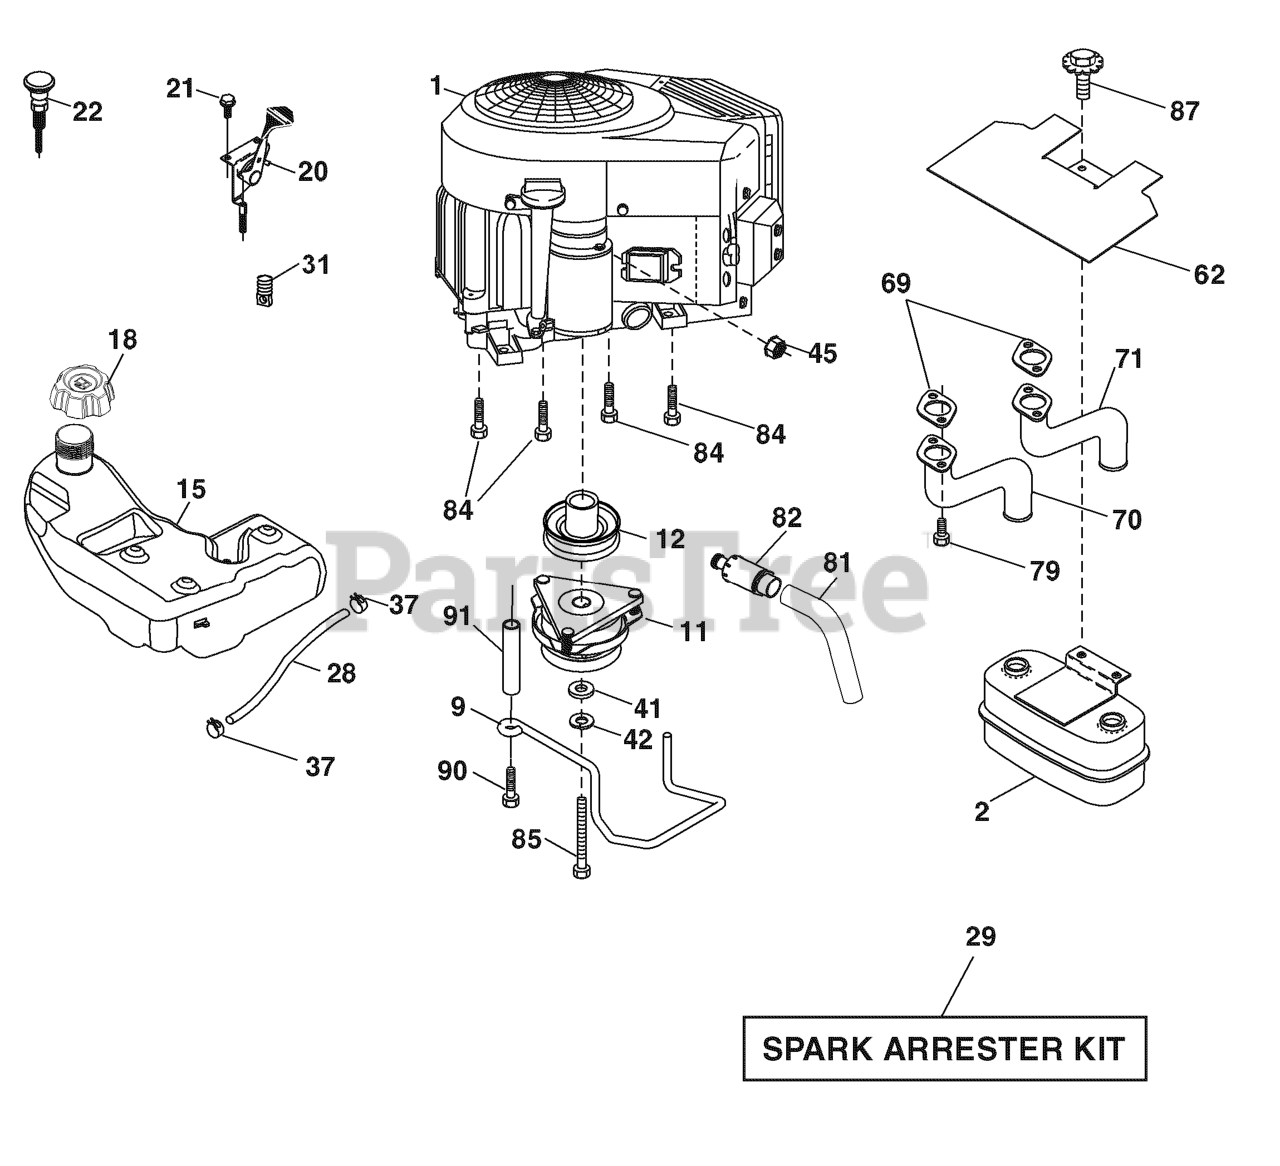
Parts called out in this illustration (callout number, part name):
2	MUFFLER.TWIN.CYL.LOW.TONE
9	KEEPER.BELT.ENGINE.4.2
11	CLUTCH MZ ZTR GT.48/54"1.125"
12	PULLEY ENGINE
15	TANK.FUEL.4GAL
18	CAP.FUEL.TANK.3"GREY
20	THROTTLE CABLE
21	SCREW.#10 X 0.750.BOS
22	CONTROL.CHOKE.ERGO.PUSH-IN.BLA
28	LINE.FUEL.64"REAR.EMIS
29	KIT.SPARK ARRESTOR 794945 B&S
37	HOSE CLAMP
42	LOCKWASHER
45	NUT
62	RP SHIELD HEAT MUFFLER
69	GASKET.MUFFLER
70	RP.EXHAUST.TUBE.LH.BS/TWIN
71	EXHAUST.TUBE.RH.BS/TWIN
79	SCREW.SOCKET.HEAD.5/16-18
81	TUBE, DRAIN OIL ASM.
82	PLUG DRAIN OIL EASY
84	SCREW.3/8-16
85	BOLT HEX 7/16-20 X 3.75 GR. 5
86	NUT.HEX.FLANGE.TOPLOCK
87	BOLT.5/16-18UNCX1.W/SEMS.BLK
90	SCREW 3/8-16X1
91	BUSHING.1.375OD
